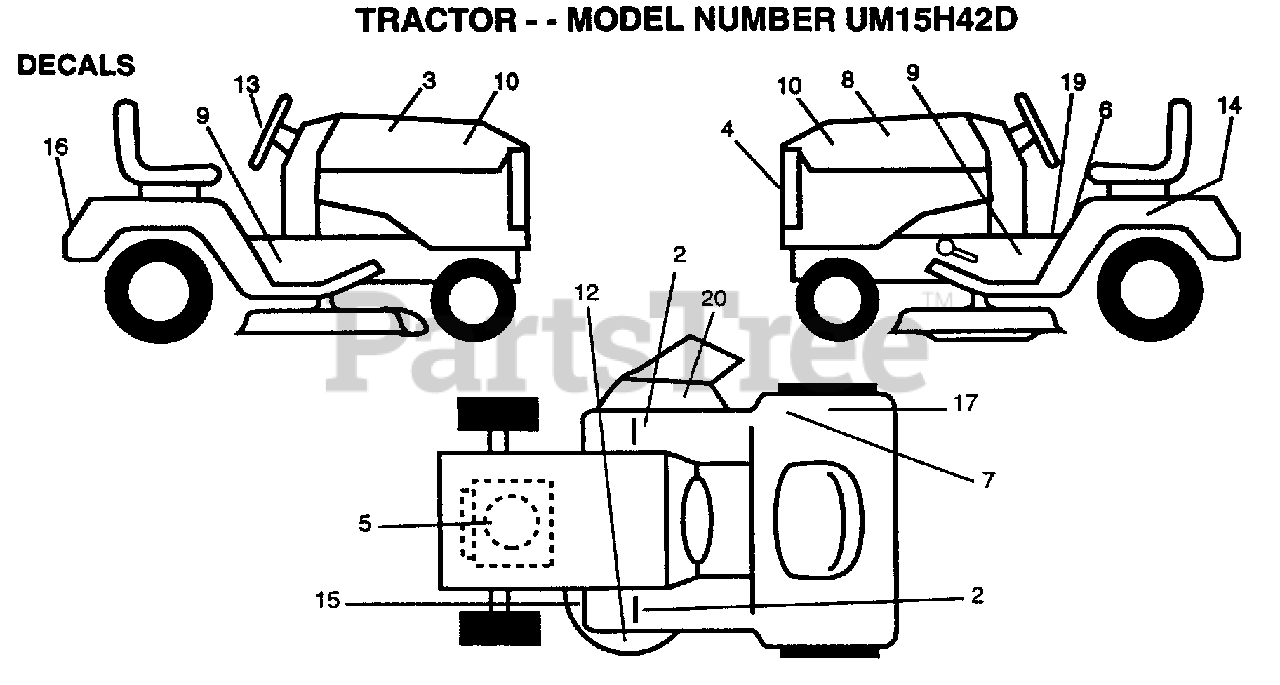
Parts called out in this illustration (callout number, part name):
2	"PAD,FOOTREST"
3	DECAL HD RH RALLY
4	DECAL LIGHTBOX
6	DECAL.READ.O.MANU
7	DECAL.EURO.ST.CE.
8	DECAL HD LH RALLY
9	DECAL CHAS 42 HYD
10	DECAL HD INS 15HP
13	"DECAL,STR WHL"
14	DECAL.BATRY.3-3908
15	DECAL
16	FENDER DECAL
19	DECAL BRAK PARK
20	DECAL.DANGER.CUTF
